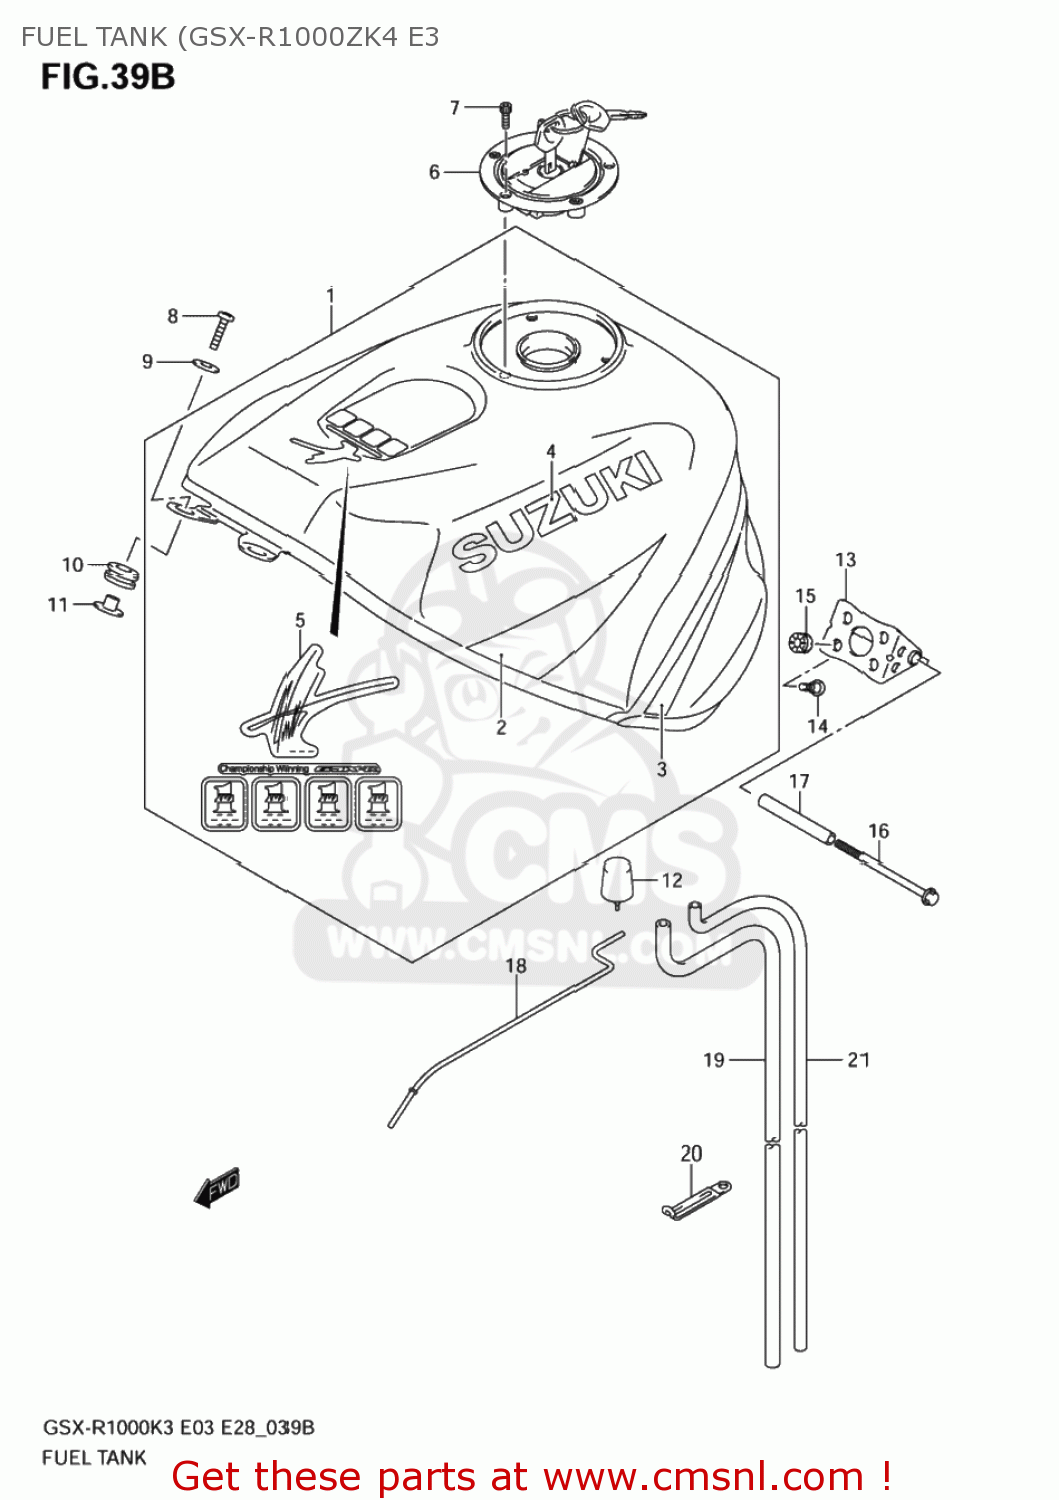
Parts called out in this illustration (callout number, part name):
1	TANK ASSY,FUEL
2	TAPE SET,FUEL TANK UPR
3	TAPE SET,FUEL TANK LWR
4	EMBLEM,FUEL TANK
5	EMBLEM,TANK UPR
6	CAP SET,FUEL TANK
7	BOLT(5X20)
8	SCREW(6X25)
9	WASHER(6.5X22X1.6)
10	CUSHION,FUEL TANK FR
11	SPACER,FUEL TANK FR
12	CUSHION,FUEL TANK RR
13	BRACKET,FUEL TANK NO.1
14	SCREW,FUEL TAN
15	CUSHION
16	BOLT(6X110)
17	SPACER,FUEL TANK RR
18	STAY,FUEL TANK
19	HOSE,WATER DRAIN
20	CLAMP(L:65)
21	HOSE,FUEL TANK BREATHER
